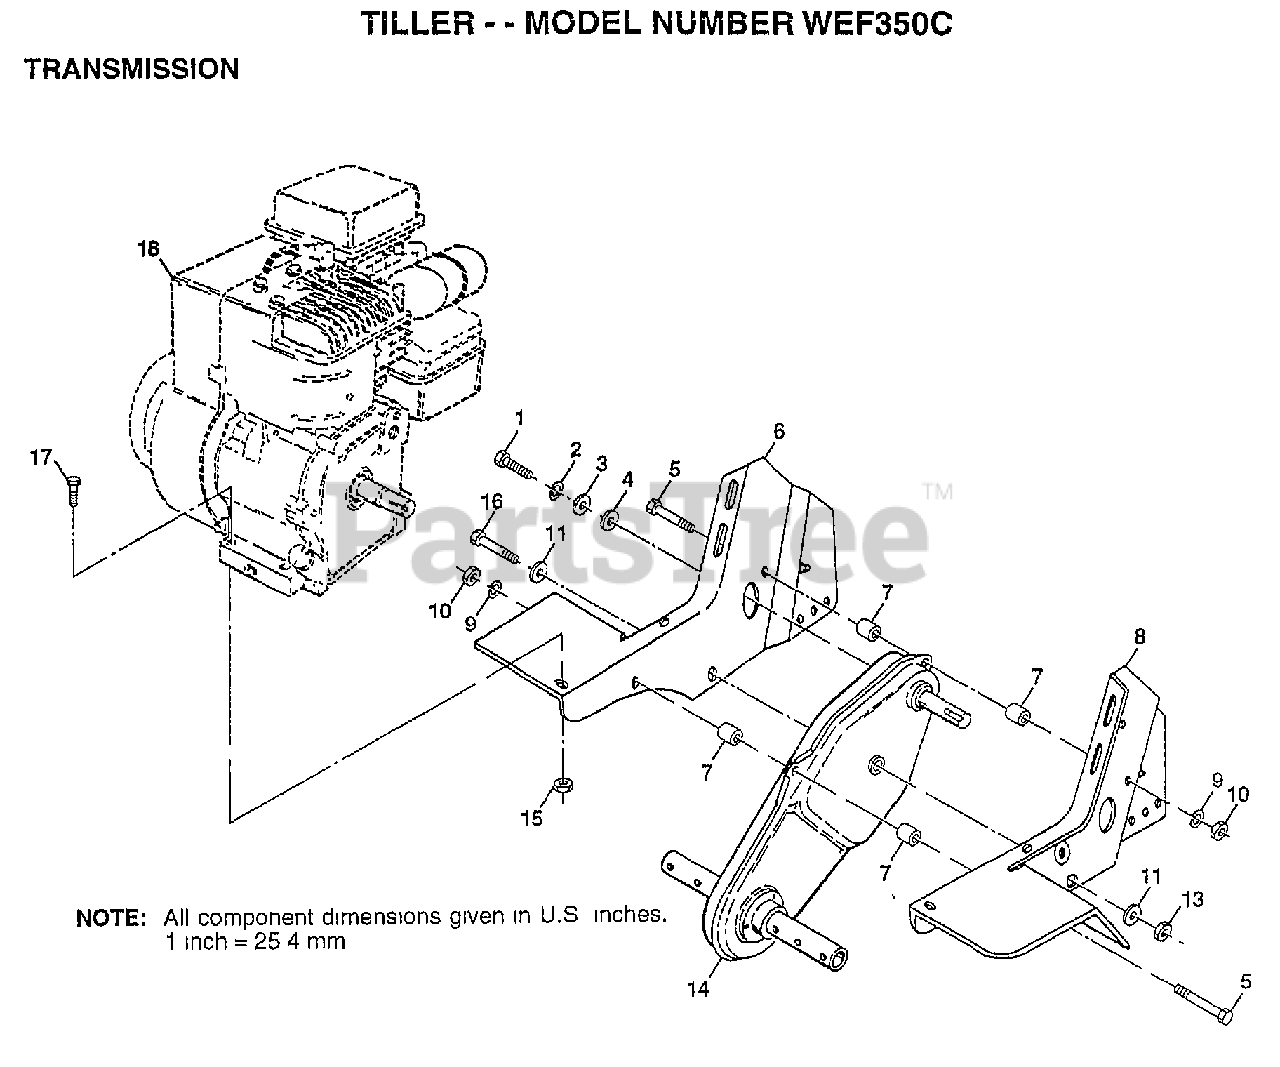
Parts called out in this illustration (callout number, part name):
1	BOLT
2	LOCKWASHER
3	WASHER
4	WASHER
6	BRACKET.ENGINE.RH
7	SPLIT SPACER RT
8	BRACKET.ENGINE.LH
9	LOCKWASHER
10	NUT.HEX.5/16-18
11	WASHER
13	NUT
16	BOLT HEX 3/8-16
17	BOLT.HEX.5/16-1.5
